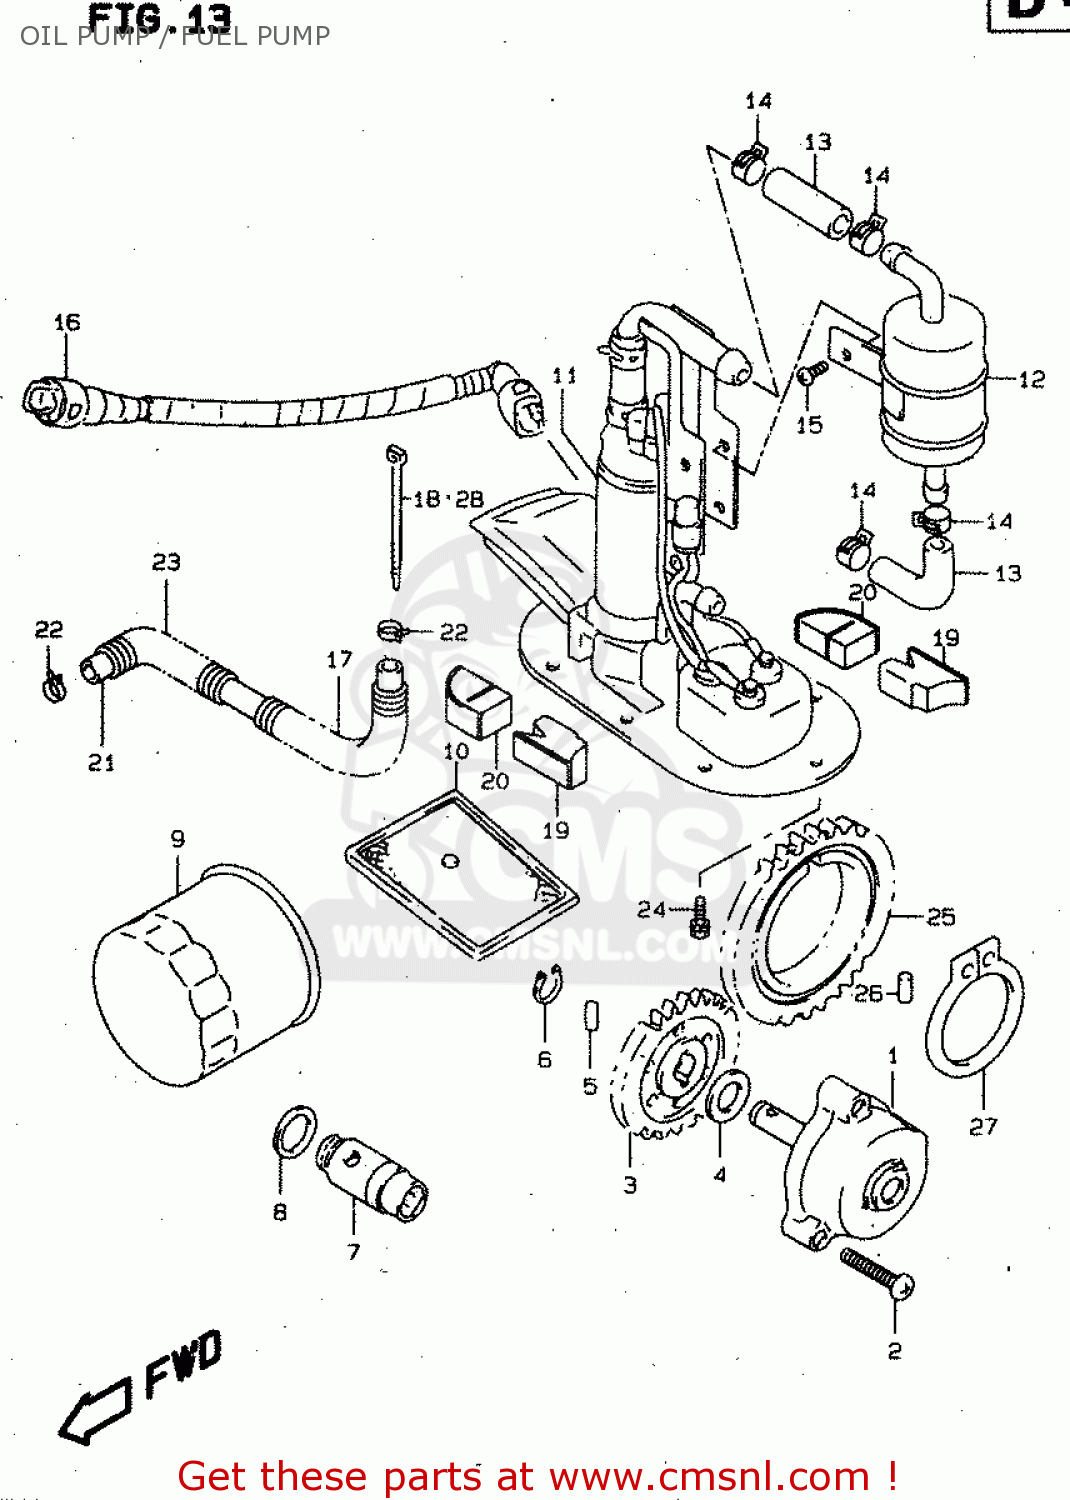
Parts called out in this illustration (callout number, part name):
1	PUMP ASSEMBLY,ENGINE OIL
2	SCREW
3	GEAR,OIL PUMP DRIVEN
4	SHIM(10X18X0.5)
5	PIN(4X15.8)
6	CIRCLIP,10MM
7	VALVE ASSY,OIL RELIEF
8	GASKET(16X22X2) (NAS)
9	FILTER ASSEMBLY,ENGINE OIL
10	STRAINER,ENGINE OIL
11	PUMP ASSY,FUEL
12	FILTER,FUEL
13	HOSE(7.6X14X600)
14	CLIP
15	SCREW
16	HOSE,FUEL
17	PROTECTOR,FUEL RETURN NO,2
18	CLAMP(L:80)
19	SPACER
20	SPACER,FUEL PUMP NO.2
21	HOSE(5.4X11.4X600)
22	CLIP
23	(CA) SPRING
24	BOLT
25	GEAR,ENG OIL PUMP DRIVE
26	PIN(6X6)
27	CIRCLIP
28	CLAMP(L:125)
